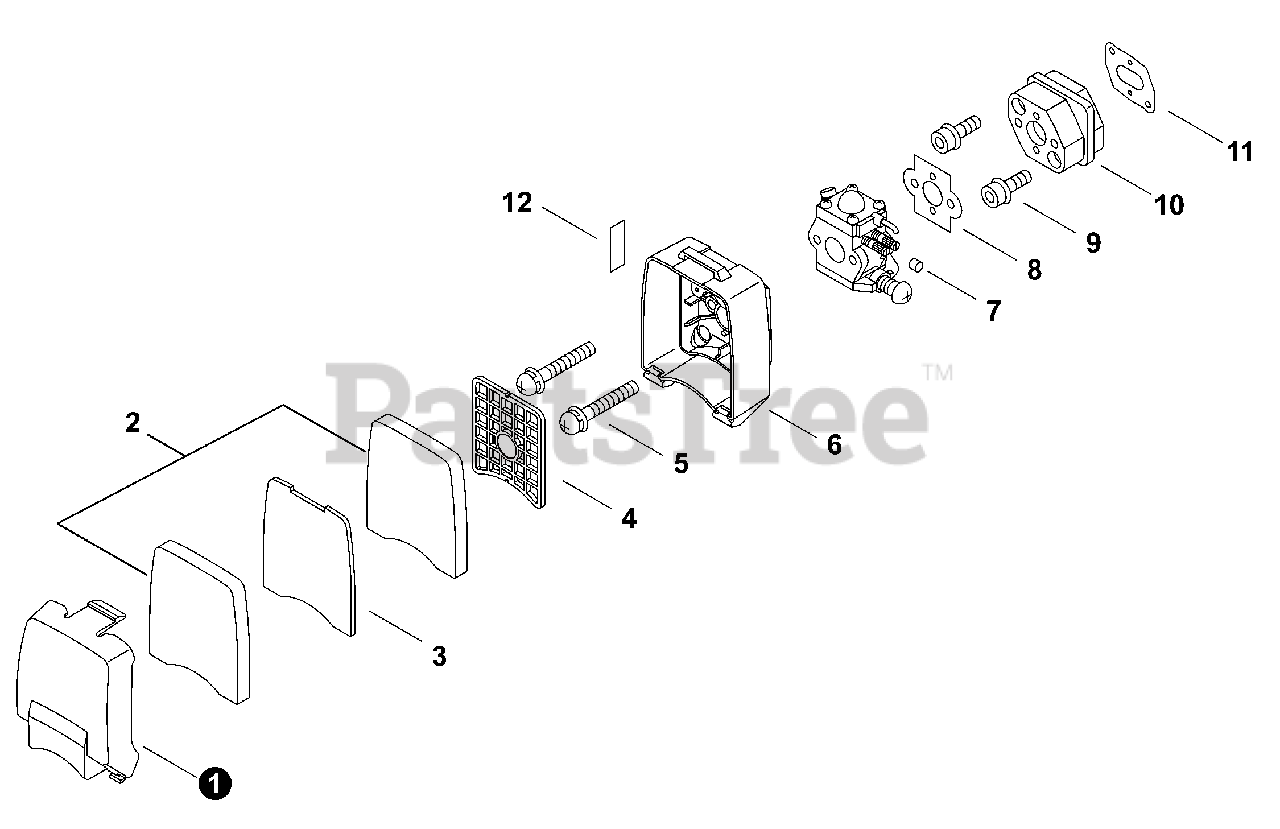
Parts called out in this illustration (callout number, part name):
1	COVER, AIR FILTER
2	FILTER, AIR
3	FILTER, AIR
4	GRID, AIR FILTER
5	SCREW 5×50
6	CASE, AIR FILTER
7	CAP, LIMITER
8	GASKET, CARBURETOR
9	BOLT 5×25
10	INSULATOR, INTAKE
11	GASKET, INTAKE
12	LABEL, CHOKE
